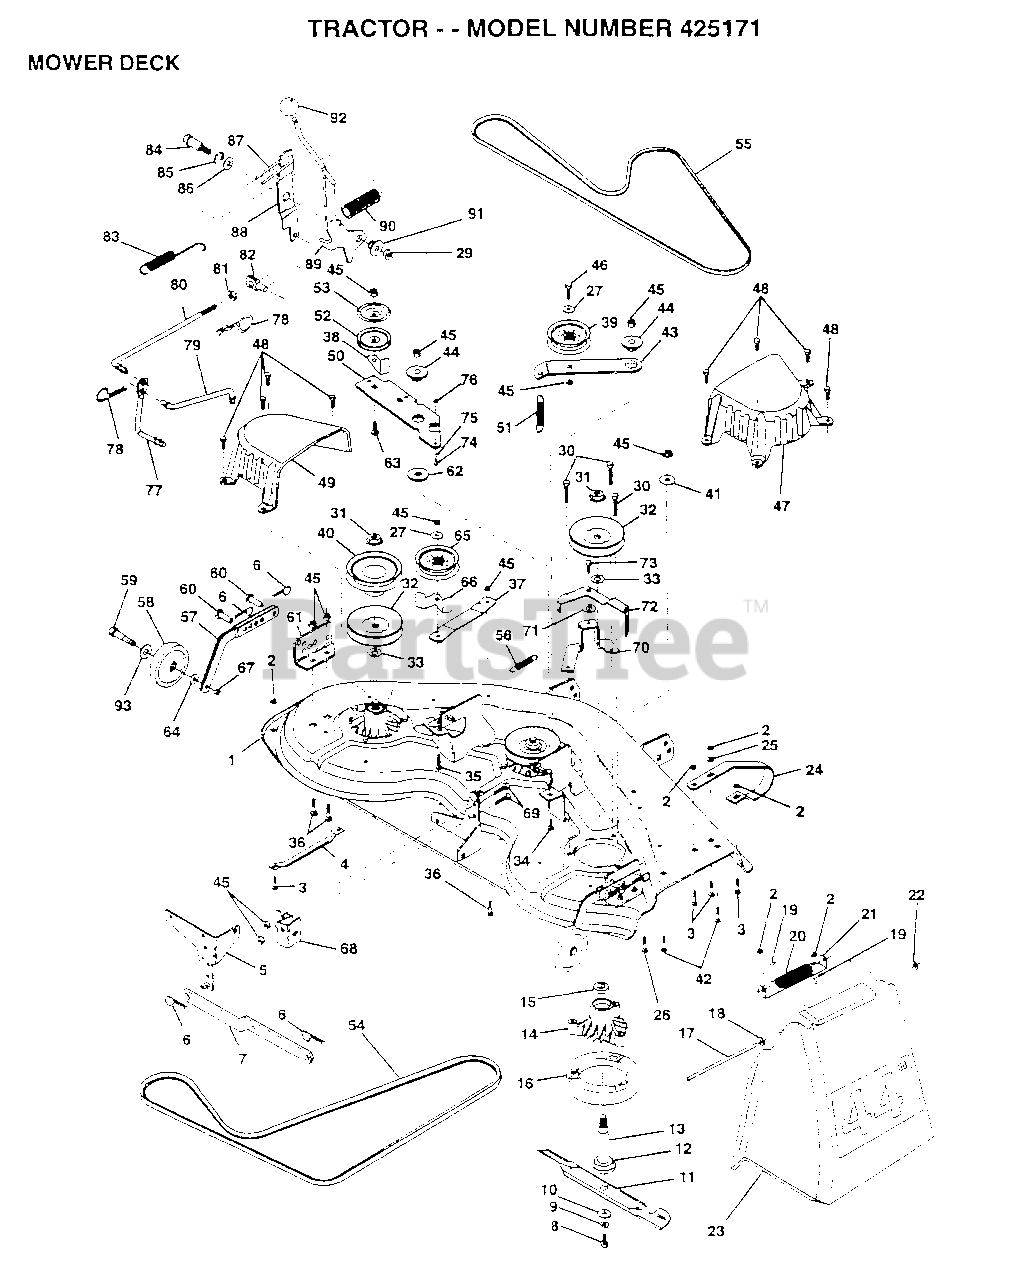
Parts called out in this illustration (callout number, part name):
1	"DECK ASM WELD44"""
4	RUNNER-LH M
5	BRKT.ASM.SW.44/50
8	BLADE BOLT
10	WASHER.HARD.BLADE
11	"BLADE.44"" HIPERF"
12	BEARING.BALL
13	SHAFT.ASM.W/BRNG
14	HOUSING.MAND.44.V
15	BEARING
16	STRIPPER RND MWR
17	ROD-HINGE T
18	WASHER
19	CAP-SLEEVE LT
20	SPRING TORSION
21	BRKT DEFLECTOR
22	NUT PUSH M
23	DEFLECTOR SHIELD
24	RUNNER.RH
25	WASHER M
26	BOLT
27	WASHER
29	NUT
33	WASHER
34	BOLT.3/8-14X1.25
35	BOLT
36	BOLT D
37	STIFFENER.ARM.IDL
38	KEEPER BELT IDLER
39	FLAT IDLER PULLEY
40	"PULLEY.DRIVEN.44"""
42	BOLT
43	"ARM.IDLER.SEC.44"""
44	SPACER RETAINER
47	"COVER.MAND.RH.44"""
48	SCREW.1/4-20X5/8
49	COVER.MANDREL.LH
50	ARM.IDLER.PRIMARY
51	"SPRING.SEC.44""VEN"
52	PULLEY.IDLER.VGRO
53	SHIELD.IDLER.44.V
54	BELT-V MOWER PRIM
55	BELT-V.88.12.MW
56	"SPRING,EXTENTION"
57	BAR.ASM.GUAGE.WHL
59	BOLT M
60	PIN.CLEVIS
61	BRACKET.GUAGE.WHL
62	HARDENED WASHER
63	BOLT.3/8-16X1.50
64	WASHER
65	IDLER-FLAT T
67	NUT
68	BRACKET PVT MCH
70	"BRACKET SUPT 44"""
71	HARD SMALL WASHER
72	ARM BRAKE ASM
73	BOLT.SHLD.5/16-18
75	SHOULDER BOLT
76	LOCKNUT
77	PIVOT ROD
78	RETAINER M
79	ROD CLUTCH SECON
80	ROD.CLUTCH.PRIM44
81	NUT
82	TRUNION ADJ
83	RETURN SPRING
84	SHOULDER BOLT
85	RING
86	WASHER
87	SPRING KEEPER
88	CLUTCH ARM SECOND
89	LEVER.CLU.PRIM.
91	BUSHING
